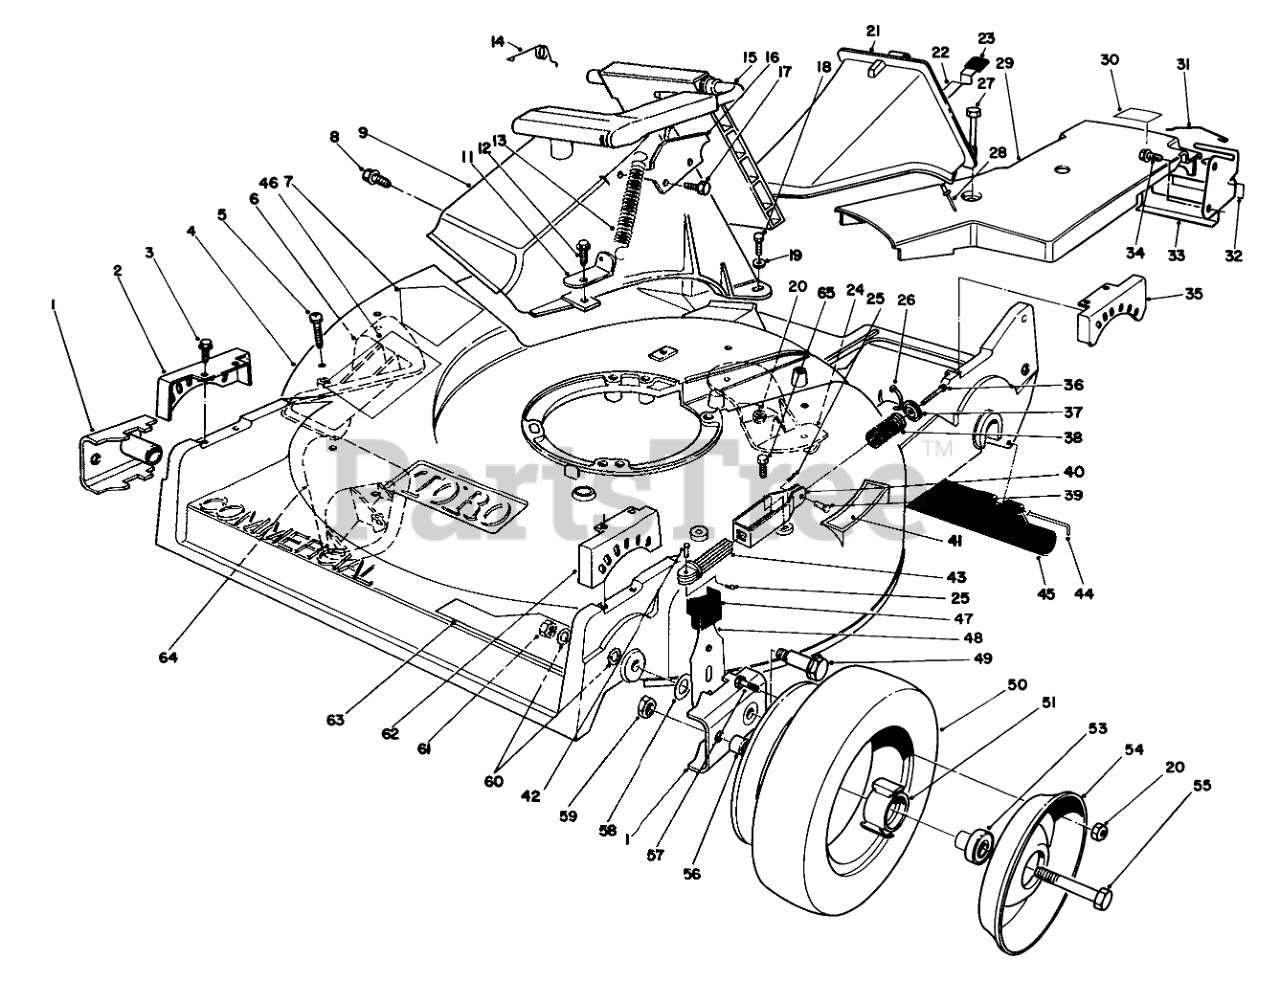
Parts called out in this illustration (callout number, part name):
1	ARM-PIVOT, FRONT
2	QUADRANT-FRONT, RH
3	SCREW-HWHTF
4	Housing-Commercial (Incl. Ref. #5-7, 24, & 64)
5	SCREW-PPH
6	KICKER-RH
7	DECAL-DANGER
8	SCREW AND WASHER ASM
9	DISCHARGE TUNNEL
11	BRACKET-SPRING
12	SCREW-HWH
13	SPRING-DOOR
14	RETAINER-DOOR
15	DOOR ASSEMBLY
16	DOOR LATCH PLATE
17	SCREW-PLASTITE
18	SCREW-HH
19	WASHER-FLAT
20	NUT-LOCK, NI
21	Plug-Discharge (Incl. Ref. #22, 23, & 28)
22	LATCH-PLUG, DISCHARGE
23	GRIP-LATCH
24	KICKER-REAR
25	PIN-COTTER
26	TIE-CABLE
27	SCREW-HHFTF
28	RIVET-HEAD, FLAT
29	COVER-BELT
30	LABEL-GREASE
31	RETAINER-CABLE
32	DECAL-POSITION, GEAR
33	BRACKET-ADJUSTMENT, TRACTION
34	SCREW-HWHTF
35	QUADRANT-REAR, LH
36	SCREW-HWHTF
37	RETAINER-SPRING
38	SPRING
39	PIN-CABLE
40	Bracket-Spring
41	STEP PAD DECAL
42	PIN-SPRING
43	GUIDE-SPRING
44	ROD-SHIELD
45	SHIELD-TRAILING
46	DECAL - DANGER, COVERS
47	KNOB-ARM
48	FRONT SPRING ARM ASM
49	BOLT-WHEEL
51	HUB-BEARING
53	Bearing-Wheel
54	Wheel-Half
55	SCREW-HH
56	SPACER-WHEEL
57	SCREW-HH
58	WASHER-THRUST
59	NUT-LOCK, CONE
60	WASHER
61	NUT-LOCK
62	QUADRANT-FRONT, LH
63	DECAL - RECYCLER
64	KICKER-FRONT
65	SCREW-HH
